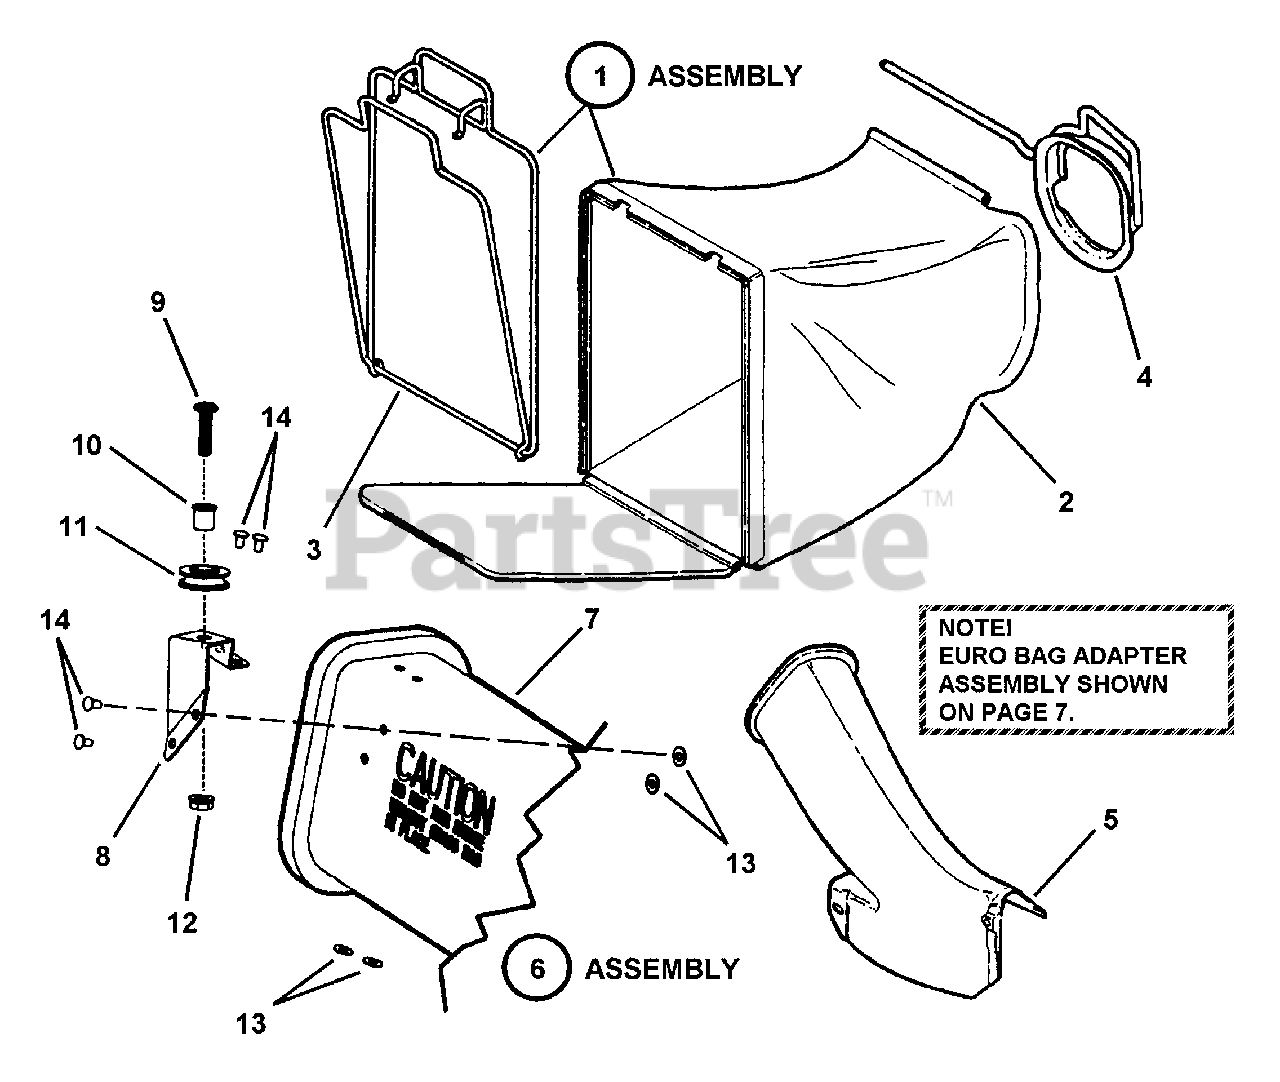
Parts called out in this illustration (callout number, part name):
1	ASSEMBLY, Grass Bag
2	BAG, Door Type (Black) (13" Wide)
3	ASSEMBLY, Bag Wire (13" Wide)
4	CONNECTOR, Grass Bag
5	ADAPTER, Bag
6	ASSEMBLY, Bag Adapter
7	ADAPTER, Bag
8	BRACKET, Rope Pulley
9	SCREW, 5/16-18 x 1-1/4" Pan Head Machine
10	BUSHING, Flange
11	PULLEY, Plastic
12	NUT, 5/16-18 Hex Flange Lock, Grade 5
13	WASHER, 15/32"
14	RIVET, 3/16 x .344
